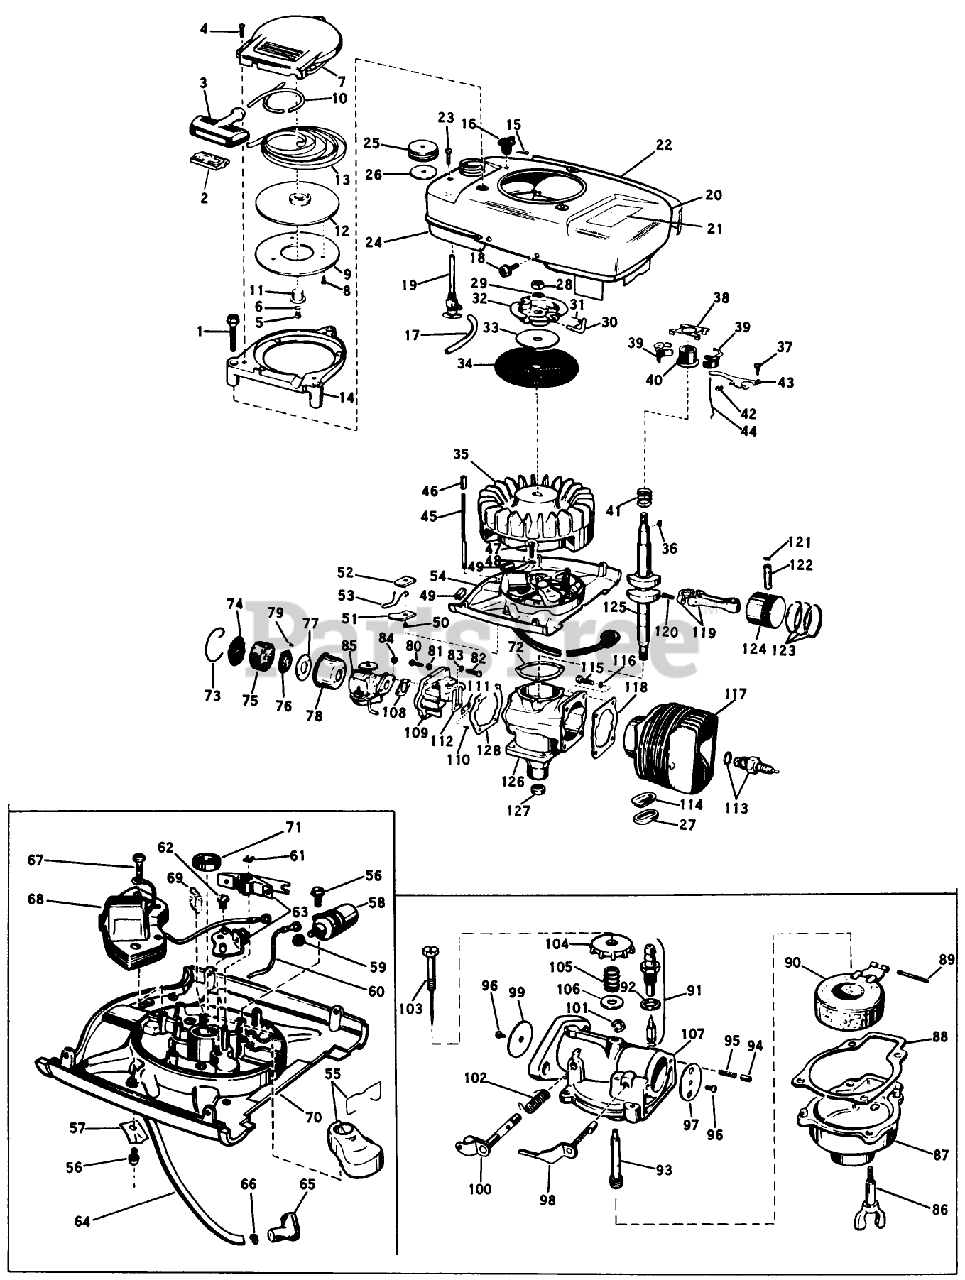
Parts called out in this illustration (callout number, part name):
5	Screw-Pulley to Cap
13	RECOIL SPRING
14	Base-Starter
15	Cotter Pin-Choke Knob
16	KNOB, CHOKE BAR
18	SCREW S
19	VALVE&SCREEN SM
22	Decal-"Lawn-Boy"
25	Gas Cap
30	PIN - STARTER
40	COLLAR S
42	WEAR BLOCK S
43	GOVERNER LEVER AY
44	GOVERNOR ROD S
50	Screw Shut-off Switch
63	BREAKER AY. S
65	Cover-Rubber
69	Oiler Wick
72	GASKET S
75	ELEMENT
77	BACK-UP PLATE
80	SCREW S
84	STOP NUT
96	Screw-Choke Disc
98	CHOKE SHAFT&LVR AY
103	NEEDLE AY. S
105	Spring-Ndl. Adj.
108	GASKET S
111	PLATE-BACKUP, REED
113	Spark Plug
120	Screw-Connecting Rod
125	Crankshaft
